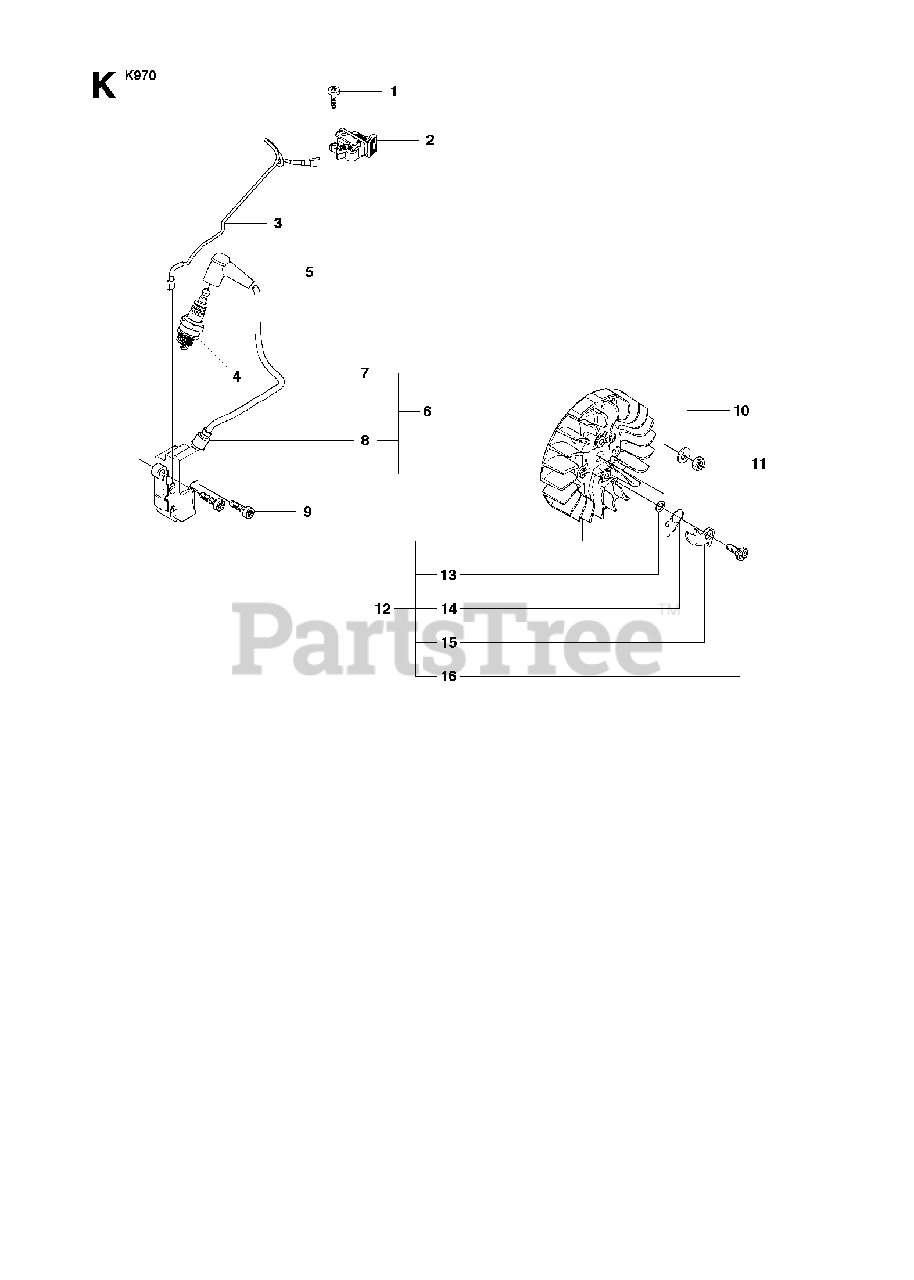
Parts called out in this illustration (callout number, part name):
1	SCREW CCRPANT
2	STOP SWITCH
5	SPARK PLUG CAP
6	IGNITION MODULE
7	IGNITION CABLE
9	SCREW ITXSCM
12	FLYWHEEL
16	SCREW
